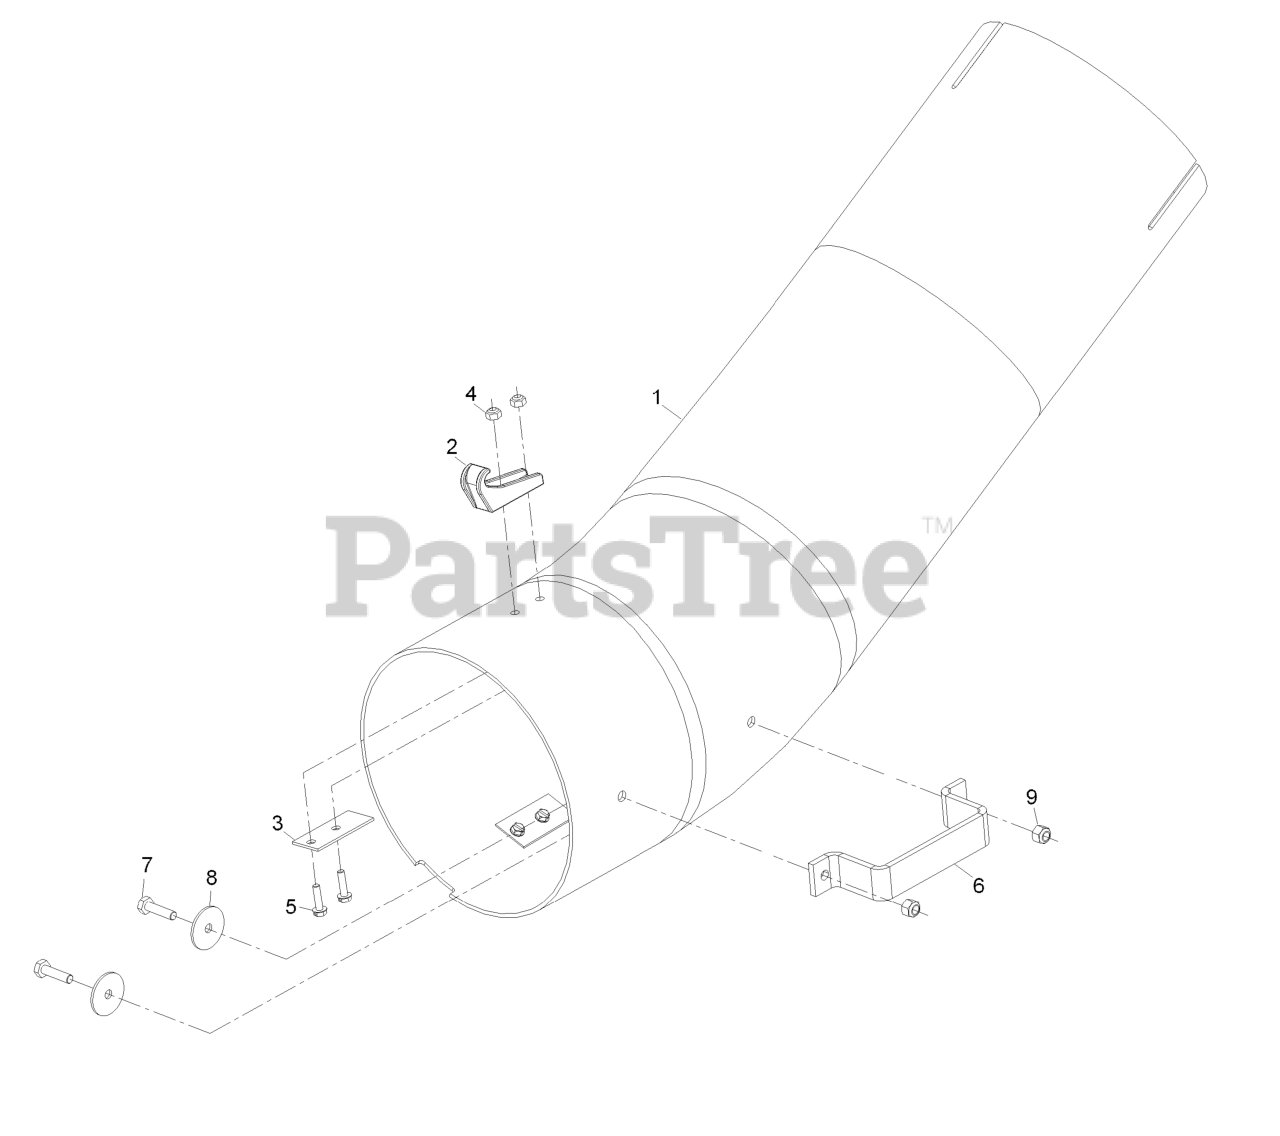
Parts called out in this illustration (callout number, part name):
2	Latch-Catch
3	Plate-Backing
4	Tube, Lower
5	Screw-HH 1/4-20 X 1
7	Nut-Nyloc #10-24
8	Nut-Nyloc 1/4-20
9	Screw-HWH #10-24 X 3/4
